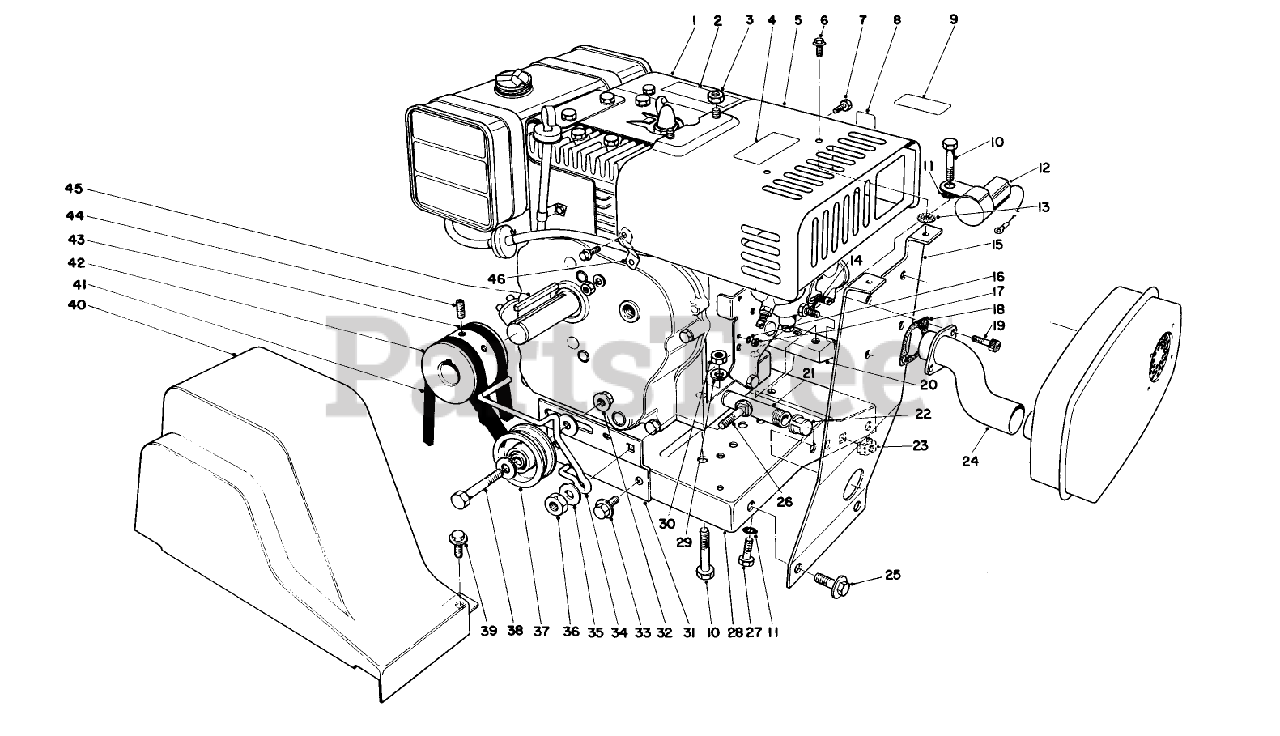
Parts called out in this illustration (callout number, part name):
1	Engine
2	Decal-Hazard
3	NUT-HEX, SIDE DEFORM
4	Bumper
5	Heater Box
6	SCREW
8	CHOKE DECAL
9	DECAL SYNCHRO BALANCE
10	SCREW-HH
11	WASHER-LOCK, INTERNAL
12	INTERLOCK MODULE
13	Washer
14	1/4-20 X 1/2 SEMS MS
15	Muffler Mounting Bracket
16	WASHER-LOCK/INT
17	NUT-LOCK
18	Gasket
19	SCREW-HSH
20	Block Engine Mounting
21	NIPPLE-PIPE
22	Pipe Cap
23	Retained Nut
24	EXHAUST PIPE
25	SCREW-HH
26	SCREW-CARR
27	SCREW-HH
28	Base-Engine
29	WASHER-PLAIN
30	NUT-LOCK, NI
31	BELT IDLER BRKT
32	NUT-HHF, WHIZ
33	SCREW-HHFTF
34	BELT GUIDE
35	WASHER-FLAT
36	NUT-LOCK, NI
37	PULLEY B
38	SCREW-HH
39	SCREW-HWH
40	BELT GUARD
41	V-BELT
42	Pulley
43	V-BELT
44	Screw-Set
46	Brace Heater Box
